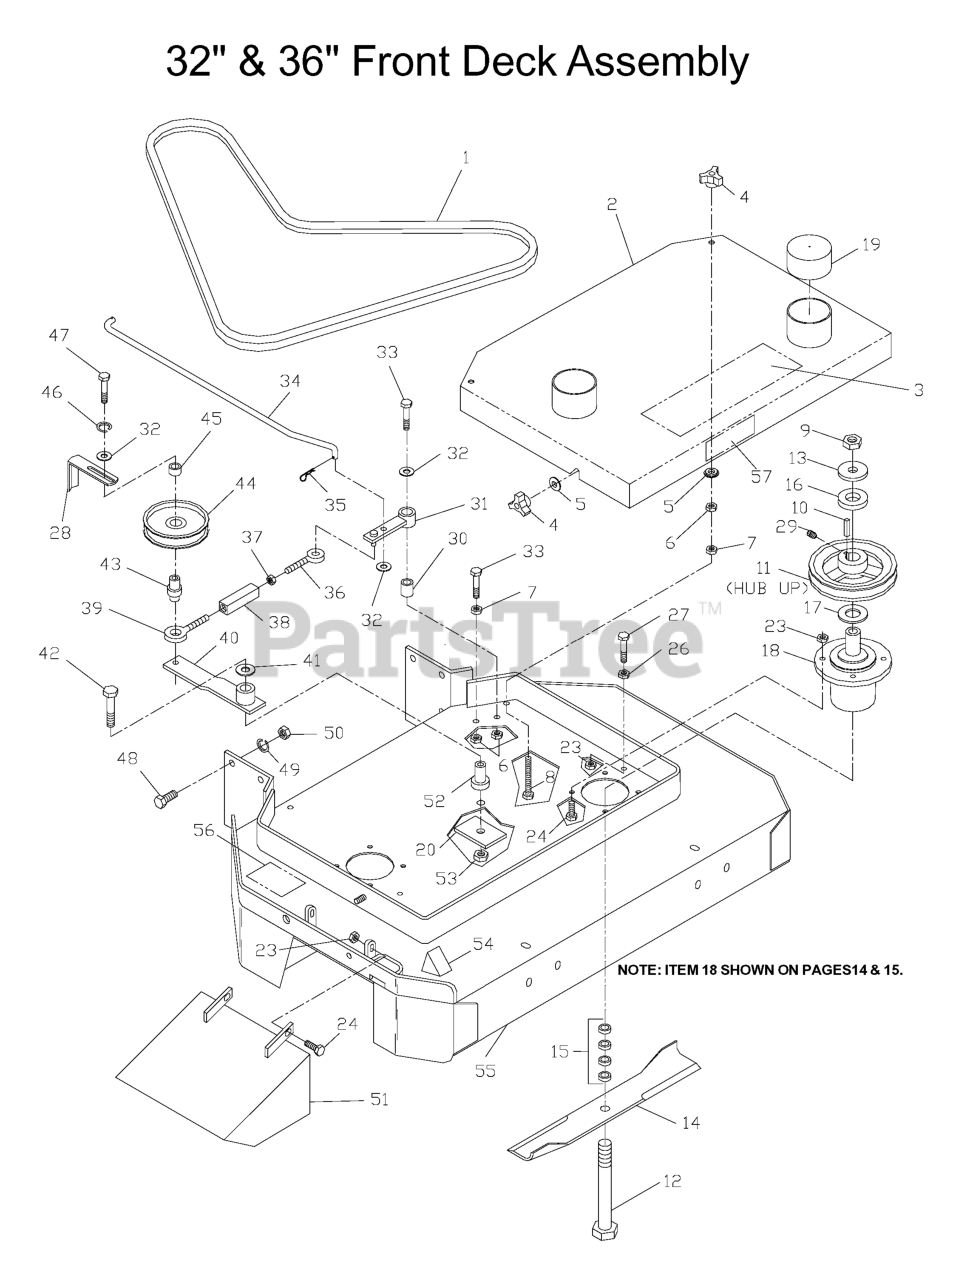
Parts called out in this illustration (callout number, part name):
1	BELT, DECK, 36"
1	BELT, DECK 32"
2	BELT SHIELD ORANGE 36"
2	BELT SHIELD 32", ORANGE
3	DECAL, HUSQ 12" BLUE
4	KNOB, THREE PRONG
5	WASHER, 3/8 SEALING
6	NUT 3/8C CENTERBLOCK
7	NUT 3/8C WHIZ
8	TAPBOLT 3/8C X 4 1/2
9	NUT 5/8F HEX
10	KEY 1/4 SQ X 1 1/8
11	PULLEY W/SETSCREWS
12	HCS 5/8F X 8 1/2
13	WASHER, SUPPORT
14	BLADE OEM 18"
14	BLADE OEM 16 1/4"
15	BLADE SPACERS
17	MACHINERY BUSHING 10 GA.
18	HOUSING ASM
23	NUT 5/16C CENTERLOCK
24	HCS 5/16C X 1
26	NUT 5/16C WHIZ
27	HCS 5/16 X 3
29	SET SCREW 5/16 NYLOC
30	BUSHING, SLEEVE
31	ENGAGEMENT ARM
32	WASHER 3/8 FLAT
33	HCS 3/8C X 2 1/4
34	BLADE ROD 36"
35	HAIRPIN #2
36	EYEBOLT, RH
37	NUT 5/16C HEX
38	TURNBUCKLE
39	EYEBOLT, LH
40	ARM WELDMENT
41	WASHER 1/2 FLAT
42	HCS 1/2C X 2 3/4
43	EYEBOLT PIVOT
44	IDLER PULLEY
46	SLW 3/8 STD
47	HCS 3/8C X 2 1/2
48	HCS 7/16C X 1 1/2
49	WASHER 7/16 LOCK
50	NUT 7/16C HEX
51	DEFLECTOR CHUTE
52	IDLER SPINDLE
53	NUT 1/2-13 HEX NYLOC ZD
54	DECAL, CPSC
55	DECK W/DECALS 32"
55	DECK W/DECALS 36"
56	DECAL, EURO SEVERING
57	DECAL, NASCAR
